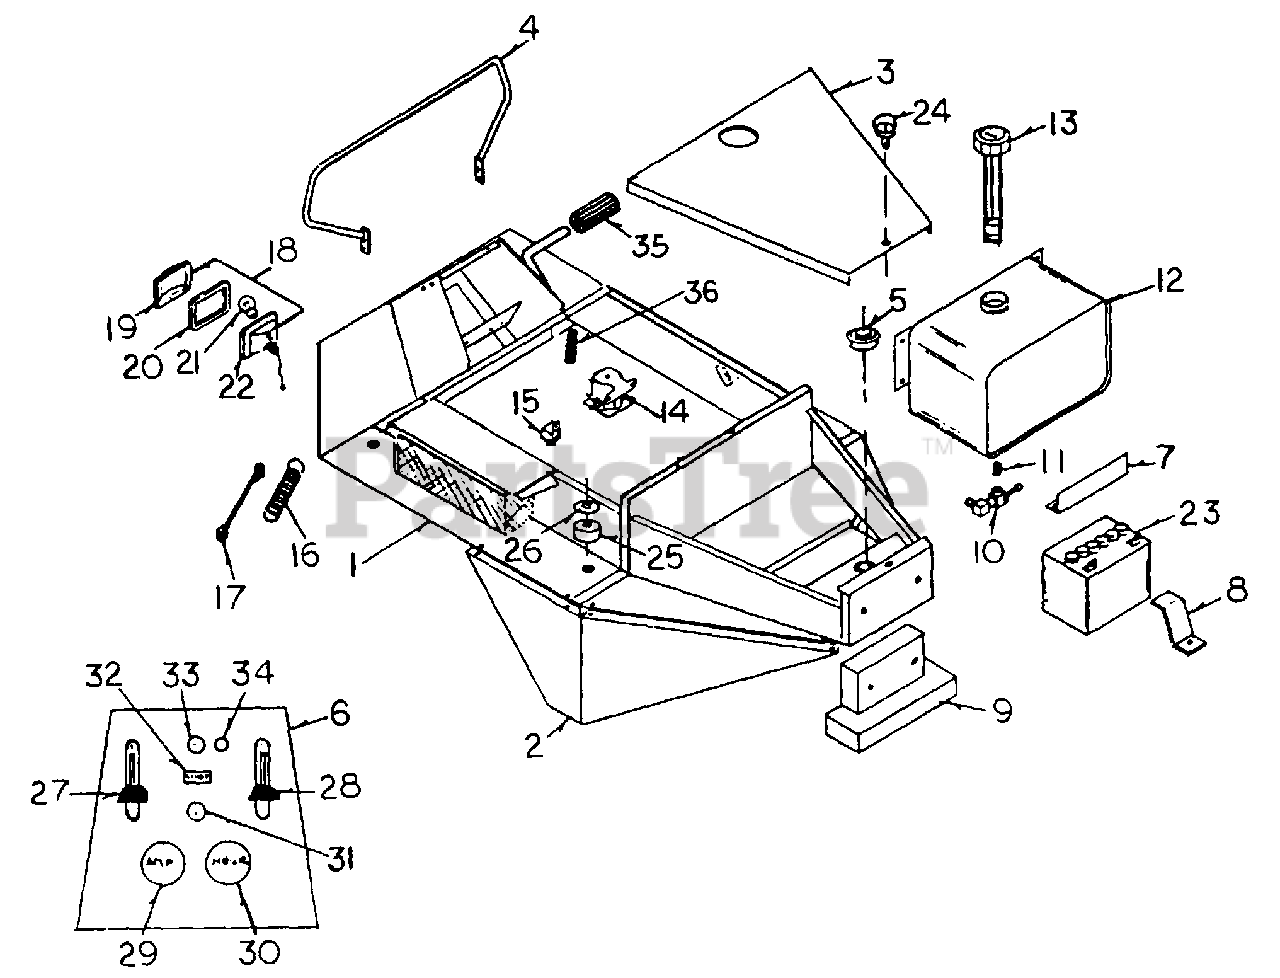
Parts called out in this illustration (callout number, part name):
1	Body
2	Fender, LH
7	Hold Down, Battery
8	Battery Post Protector
9	Tail Weight
10	Shutoff Valve, Fuel
11	Nipple, 1/8" x Close
13	Fuel Tank Cap w/Gauge
15	Relay
17	Deck Lift Cable
18	Light assembly
19	Lens
20	Gasket
21	Bulb
23	Battery
25	Rubber Body Mount
26	Body Mount Washer
28	Throttle Cable
31	Ignition Switch
32	Light Switch
33	Clutch Switch
35	Brake Pedal Pad
